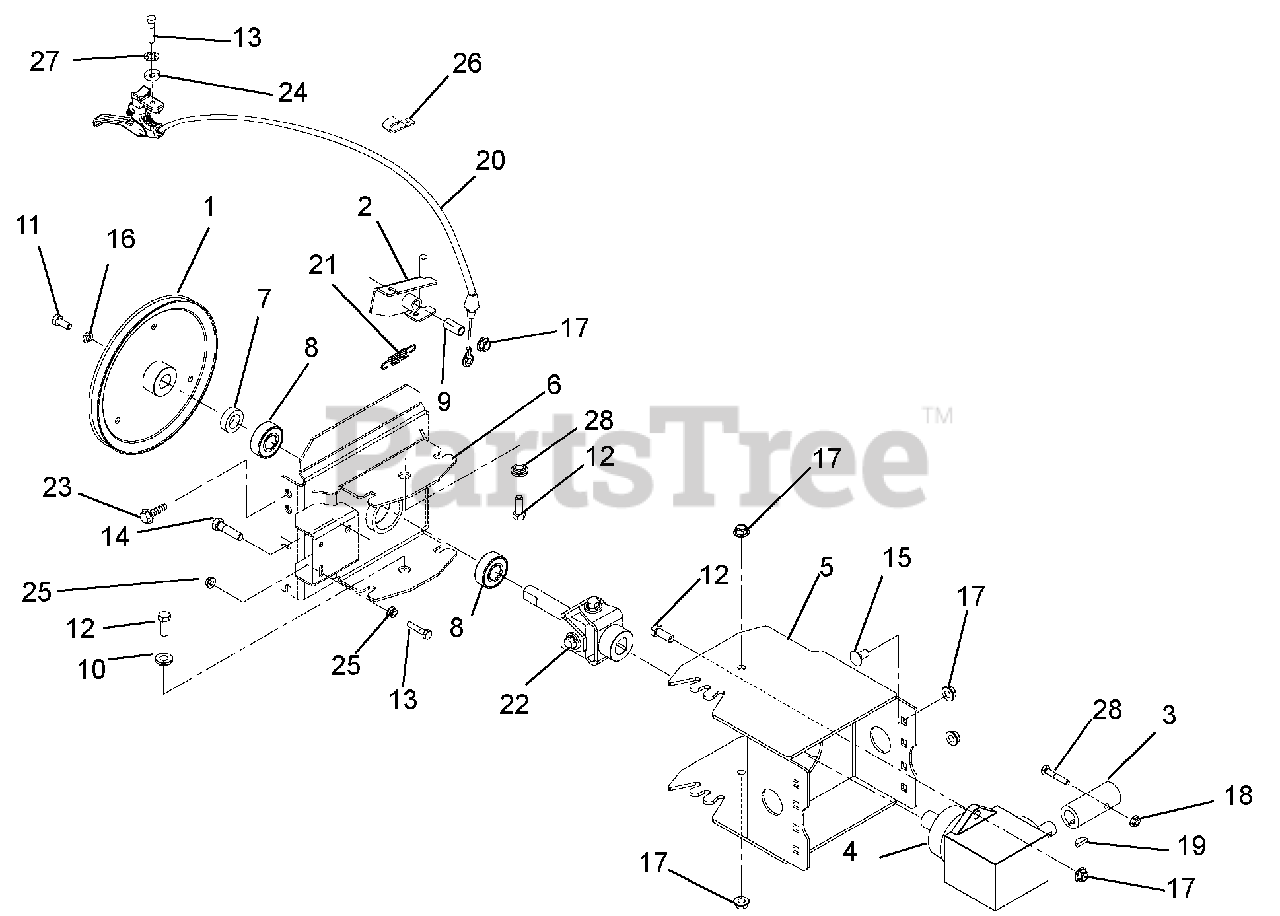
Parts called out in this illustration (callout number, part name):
1	PULLEY, 4L W/HUB, .75 X 8.5
2	ARM, PIVOT LOCK
3	HUB, COUPLING
4	GEAR BOX ASSEMBLY
5	ADAPTER WITH DECAL,BRUSH FRAME
6	ADAPTER, FRAME-20000 SERIES
7	SPACER .755X1.250X.370
8	BRG-BALL .750X1.781X.61
9	BSHG-SLV .385X.500X1.045
10	BSHG-FLG .406X.88X.270X.140
11	BLT-HEX .31-24X.75 YWZC GR5
12	@BLT-HEX .38-16X1.00 GR5 YWZC
13	@BLT-HEX .25-20X1.50 GR5 YWZC
14	@BLT-HEX .38-16X1.75 GR5 YWZC
15	@BLT-RDHDSQNK .38-16X.75 G5YZ
16	WSHR-LK .312X.097 HVY YWZC
17	@NUT-LK-TOP-FLG .38-16 YWZC
18	@NUT-LK-TOP-FLG .25-20 YWZC
19	KEY-WDRF .188X.75X.313 SAE 9
20	CABLE, REMOTE BRUSH LOCK
21	SG-TENS .06X.46X2.00
22	U-JOINT ASSY
23	@SCR-TAP .31-18X.75 HWH TR YWZ
24	SPACER, HANDLEBAR
25	@NUT-SPNLK-FLG .25-20 YWZC
26	J-CLAMP
27	WSHR-LK-INT .250 TH TYA
28	@BLT-HEX .25-20X1.75 GR5 YWZC
